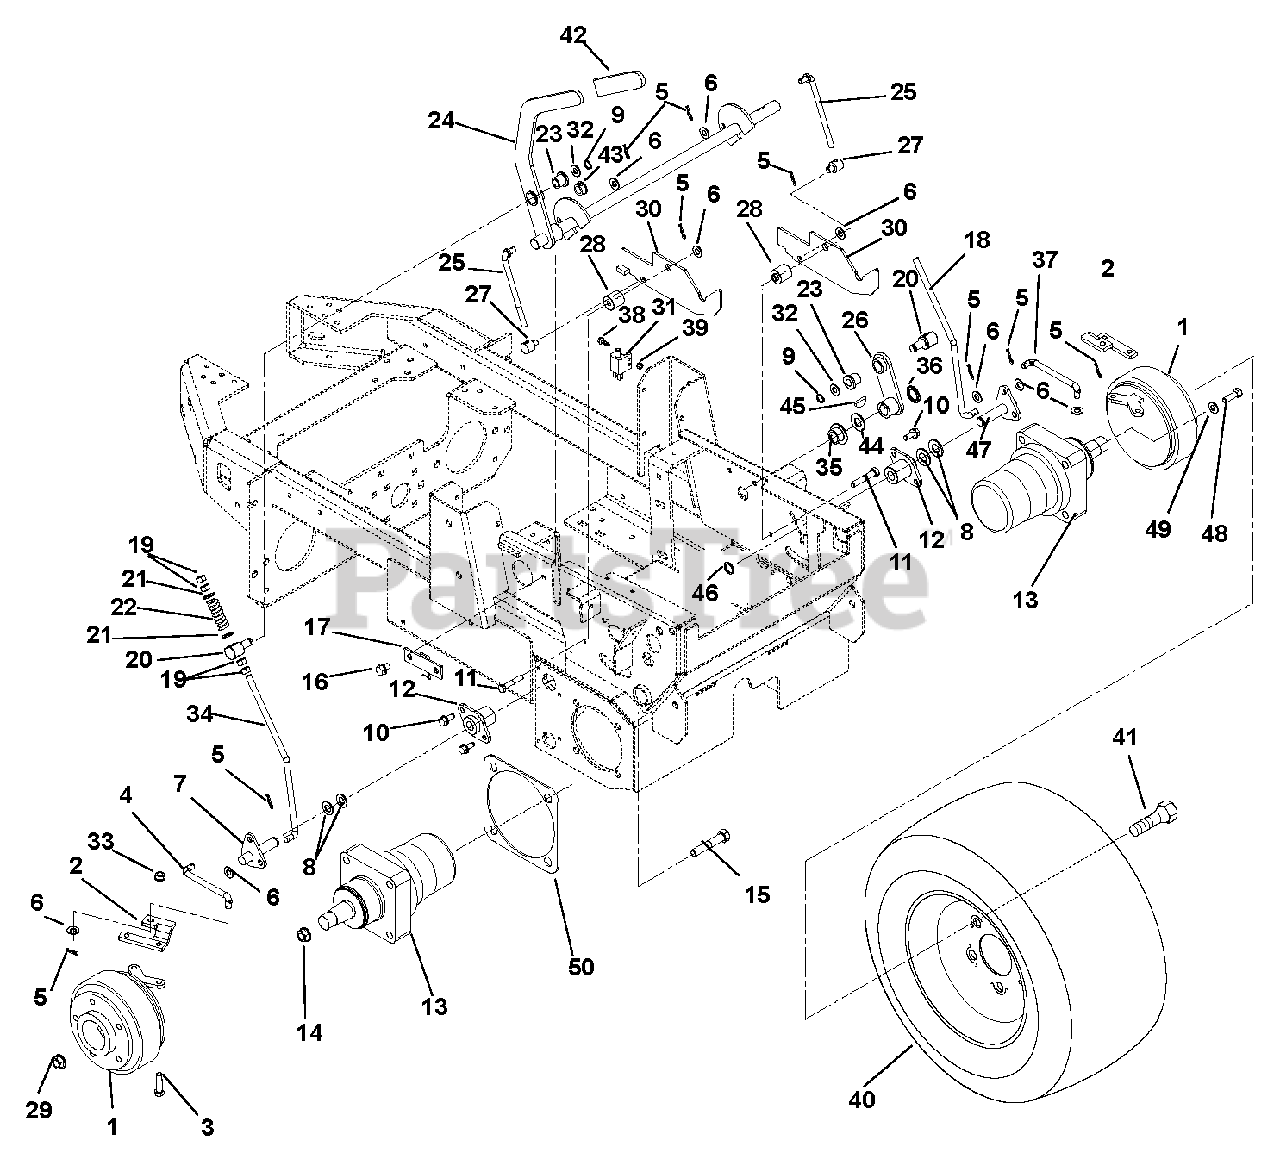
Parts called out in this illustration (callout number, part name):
1	Assembly, Brake
2	Extension, Brake
3	Bolt, Hex .31-18 x 1.00 Grade 5
4	Rod, Parking Brake Set Right Ha
5	Pin, Hair, ENDRIES #25
6	Washer, Flat Steel .406 x .812 x .0
7	Weldment, Pivot RH
8	Washer, Flat Steel .656 x 1.250 x
9	Ring, Retaining External .500 x .0
10	Screw, Tapping .31-18 x .75 Hex Washer Head Thread
11	Bolt, Hex .31-18X1.75 Grade 5
12	Bushing, Flang
13	Motor, Parker TF0360LS080AAWN
14	Nut, Nyloc Flange .50-13 YWZC
15	Bolt, Wheel Motor .50-13 x 2.75
16	Screw, Tapping .38-16 x .50 Hex Washer Head Thread Rolli
17	Weldment, Parking Brake Hold Down
18	Rod, O.C. Left Hand Brake
19	Nut, Hex .38-16
20	Trunnion, Pivot
21	Bushing, Flange .39 x .53 x .38 x 1.00
22	Spring, Compressi
23	Bushing, Flange .500 x .750 x .750 x 1.000 Bracket
24	Weldment, Parking Brake
25	Rod, Brake Link .375-24 UNF
26	Weldment, Brake Lever - Left H
27	Trunnion, .375-24 UNF
28	Spacer, Neutral Latch
29	Nut, Jam Center Lock .75-16
30	Latch, Brake Lock
31	Switch, Double Pole N.O./N.O.
32	Washer, Hardened Steel THR.515 x .97 x .062
33	Nut, .31-18 Nyloc Flang
34	Rod, O.C. Right Hand Brak
35	Bushing, Flange .762 x 1.0 x .580 x 1.48 Nylo
36	Push Nut, .745 Shaft
37	Rod, Parking Brake Set Left Han
38	Screw, Machine 10-24 x .75 Hex Washer Head
39	Nut, Locking Nylon 10-24 with Insert
40	Right Hand Bar Tire, 24 x 12-12
41	Bolt, Lug Grade 8; .50-20 UNF x 1.38 YWZC
42	Grip, Handl
43	Bushing, Split .75 x .81 x .20 THK
44	Washer, Hardened Thrust .758 x 1.23 x .031
45	Key, Woodruff .19 x .75 HRD#9
46	Ring, Retaining External .625 x .0
47	Weldment, Pivot LH
48	Bolt, Hex .31-18 x 1.50 Grade 8 EP30
49	Washer, Lock .31 x .078 Regular
50	Spacer, Wheel Motor Black
